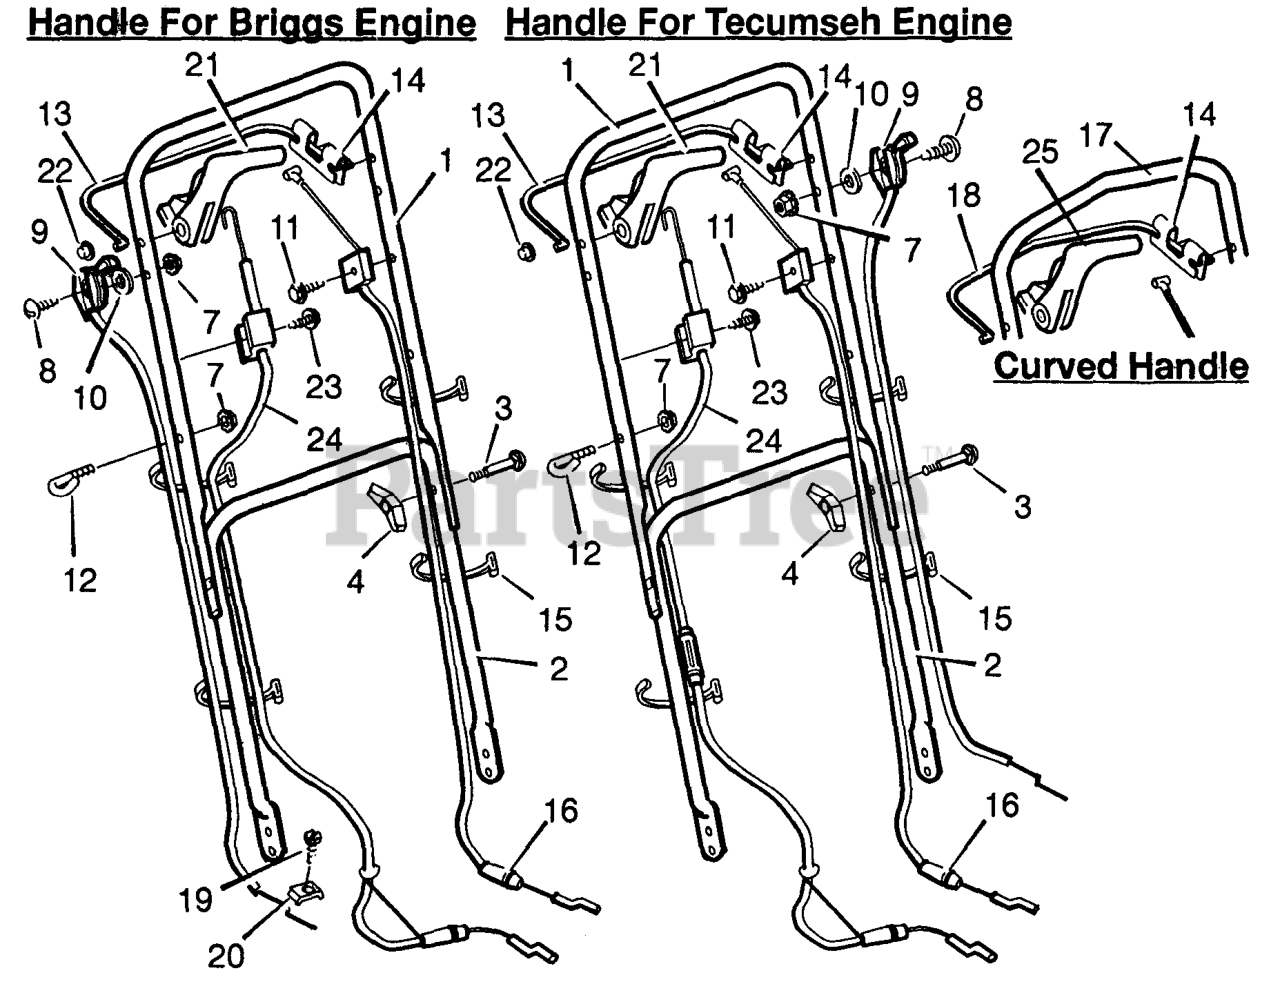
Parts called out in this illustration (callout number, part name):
1	Handle, Upper - Straight (Black)
2	Handle, Lower (Black)
4	Knob, Plastic
7	Locknut
9	Throttle Control
12	Guide, Rope
13	Stop Lever - Straight
14	Bracket, Stop Lever
15	Fastener, Cable
16	Engine Stop Cable *
17	Handle, Upper - Curved (Black)
18	Stop Lever - Curved
19	Screw *
20	Clamp
21	Lever, Drive - Straight
22	Push On Cap
24	Cable, Drive
25	Lever, Drive - Curved
